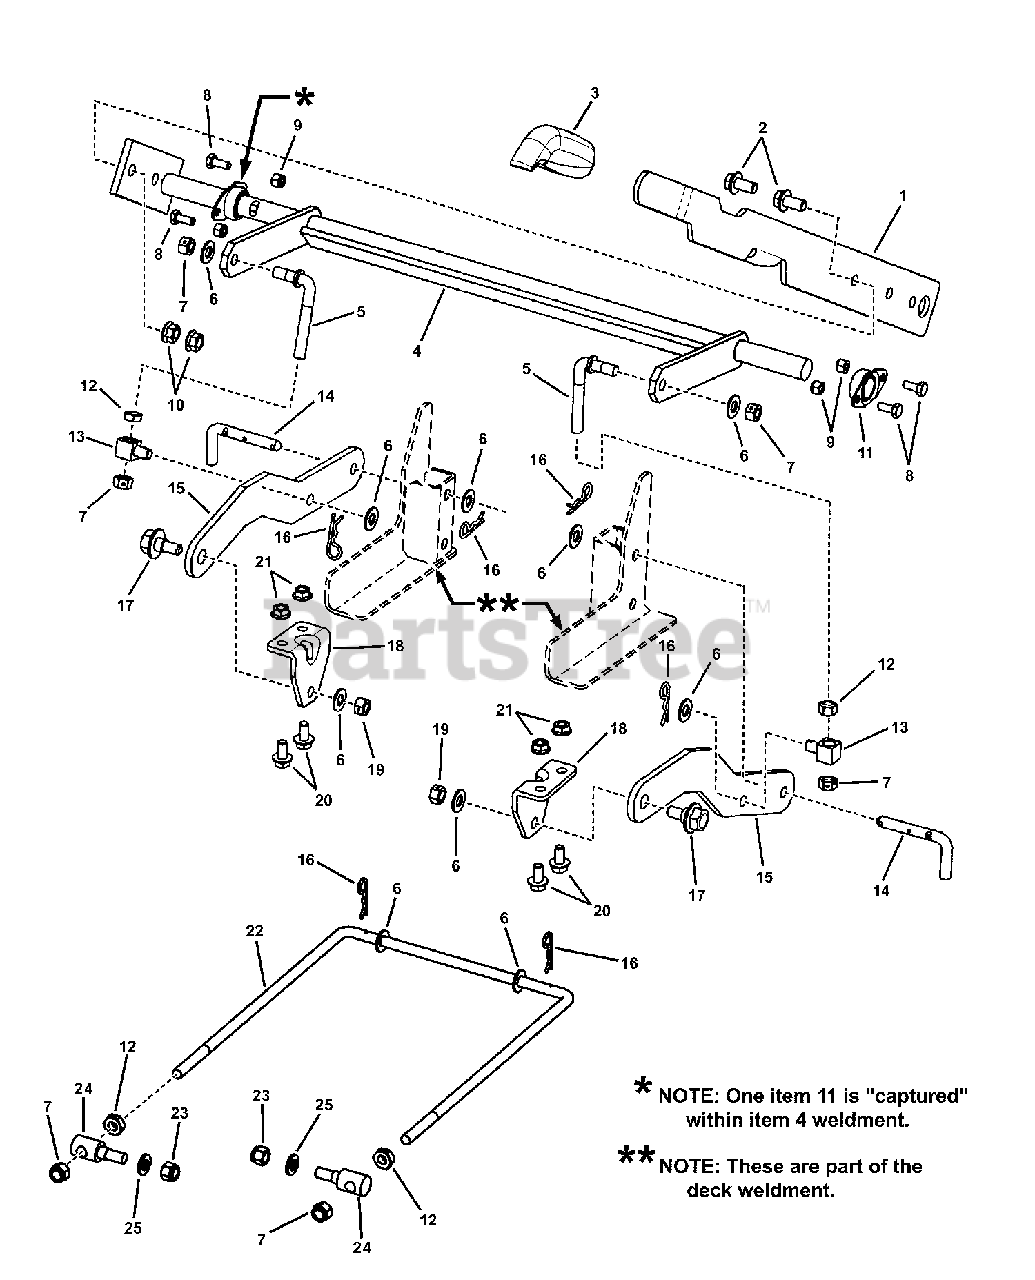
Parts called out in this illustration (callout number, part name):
1	HANDLE, Deck Lift
2	BOLT, 3/8-16 x 3/4" Hex Flange Lock, GR 5, YZ
3	HANDLE GRIP, Black Flexible (Simplicity)
4	WELDMENT, Deck Lift, 38/42
5	LINK, Leveling, 3/8-16 thread (2)
6	WASHER, 3/8" Flat SAE
7	NUT, 3/8-16 Hex Center Lock, GR 5 or B, YZ
8	SCREW, 1/4-20 x 5/8" Hex Head Cap. GR 5
9	NUT, 1/4-20 Hex Nyloc
10	NUT, 3/8-16 Hex Flange Lock
11	FLANGE BEARING, 3/4" I.D.
12	JAM NUT, 3/8-16, YZ
13	SWIVEL, Inline Brake Arm
14	PIN, Quick Hitch
15	BAR, Rear Lift, 38/42
16	HAIR PIN, 3/32 x 1-1/2"
17	SHOULDER BOLT, 3/8-24, GR 8
18	BRACKET, Deck Hanger
19	NUT, 3/8-24 Hex Center Lock
20	BOLT, 5/16-18 x 5/8" Hex Flange Lock, GR 5
21	NUT, 5/16-18 Hex Flange Lock, GR 5
22	ROD, Deck Hanger Front 38/42
23	NUT, 3/8-16 Hex Nyloc
24	SWIVEL, 3/8-16 Inline
25	WASHER, 13/32 x 1-1/4" Flat
